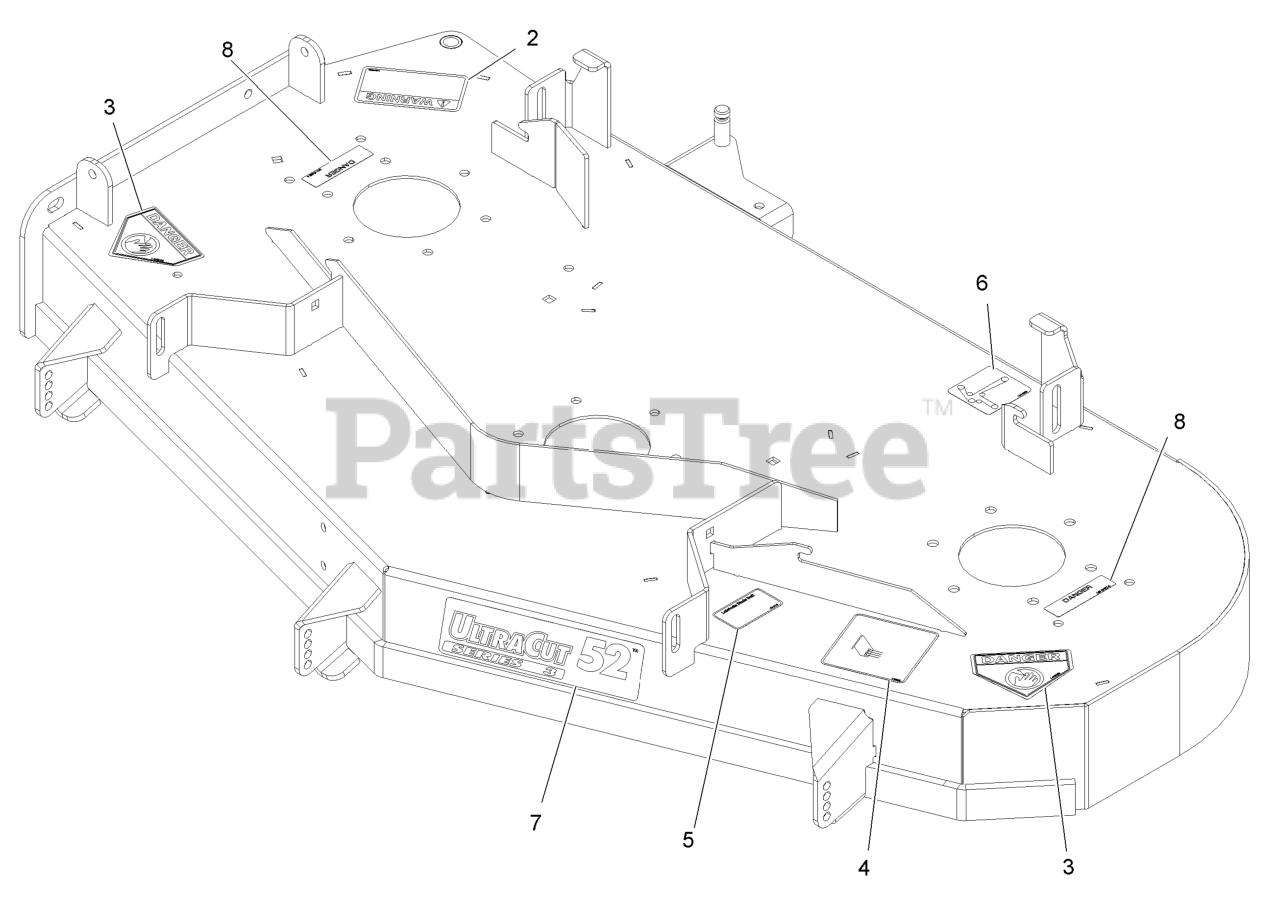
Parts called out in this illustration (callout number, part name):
2	DECAL-WARNING, DISCHARGE
3	DECAL-DANGER
4	DECAL,ANTISCALP
5	DECAL,BOLT TORQUE
6	DECAL-ROUTING, BELT
7	DECAL-ULTRACUT 52 SERIES
8	DECAL-COVER, MISSING
